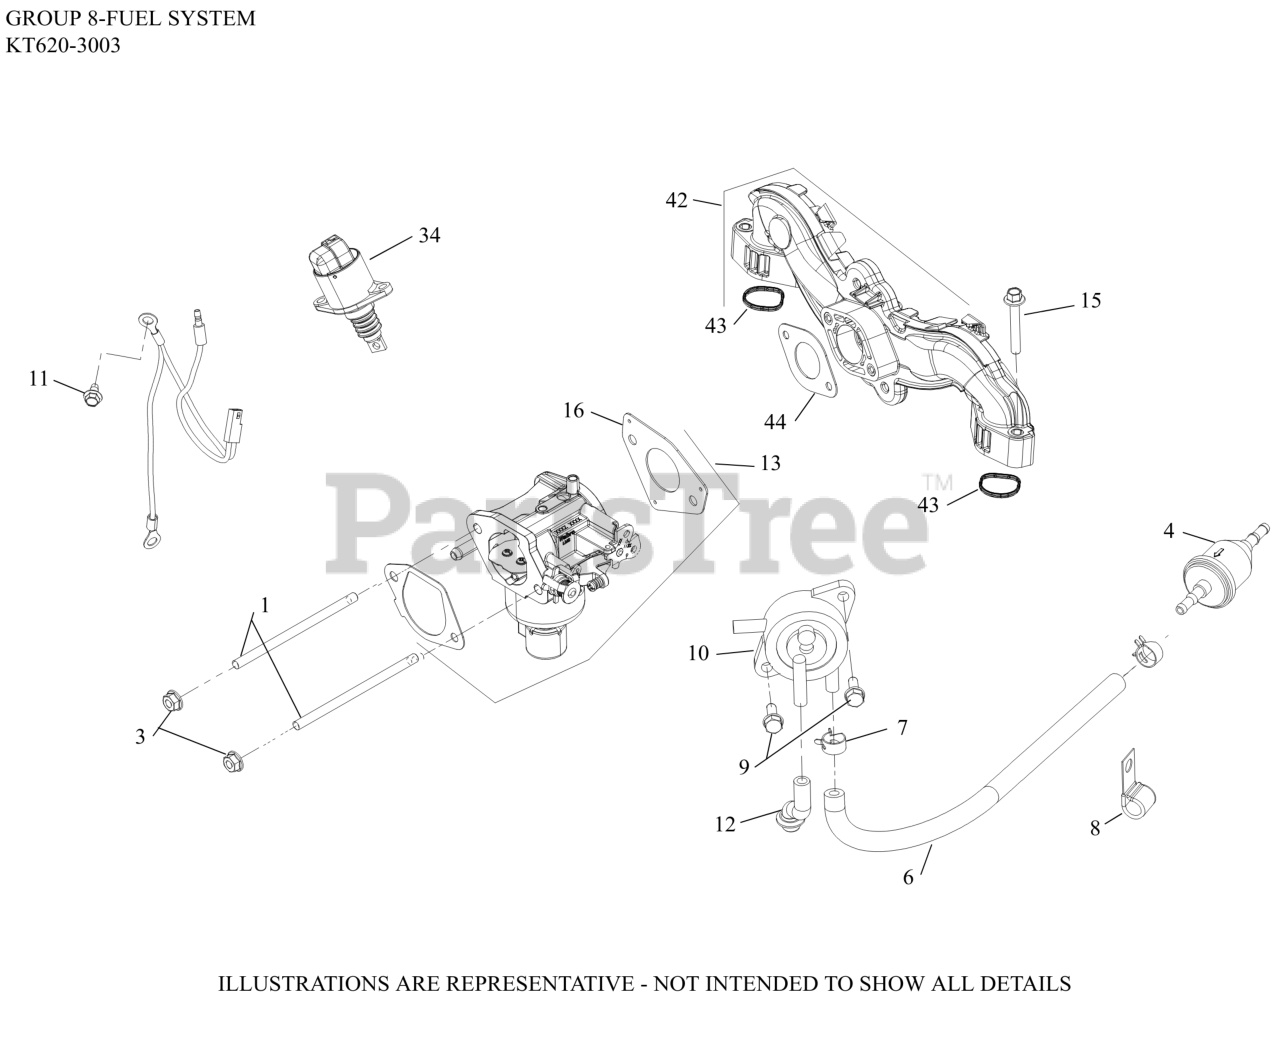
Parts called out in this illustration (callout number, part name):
3	NUT, FLG M6X1.0
4	FILTER,FUEL 51 MICRON (FUEL PUMP)
6	HOSE,LW PERM.FUEL 24.00"-USE 25 111 81-S
7	SPRING CLAMP, HOSE
8	CLIP, CABLE (KM)
9	SCREW, TAP M6X1.7X18
10	PUMP, FUEL (PULSE)-(#2539326S)
11	SCREW, THREAD FORMING
12	HOSE, PULSE PUMP(STEEL COVERS)
13	KIT,CARB(WALBRO)
15	SCREW, FLG M6X1.0X40
16	GASKET, CARBURETOR
34	ACTUATOR, LINEAR
42	INTAKE MANIFOLD W/GASKETS
43	O-RING, INTAKE PORT
44	GASKET, CARBURETOR (PIM, CV)
NI	KIT,REPAIR OVERHAUL(WALBRO)
NI	KIT,BOWL O-RING(WALBRO)
NI	KIT, HI ALTITUDE (5000 FT) 19MM
NI	KIT,SOLENOID REPAIR(WALBRO)
NI	KIT,REPAIR FLOAT(WALBRO)
